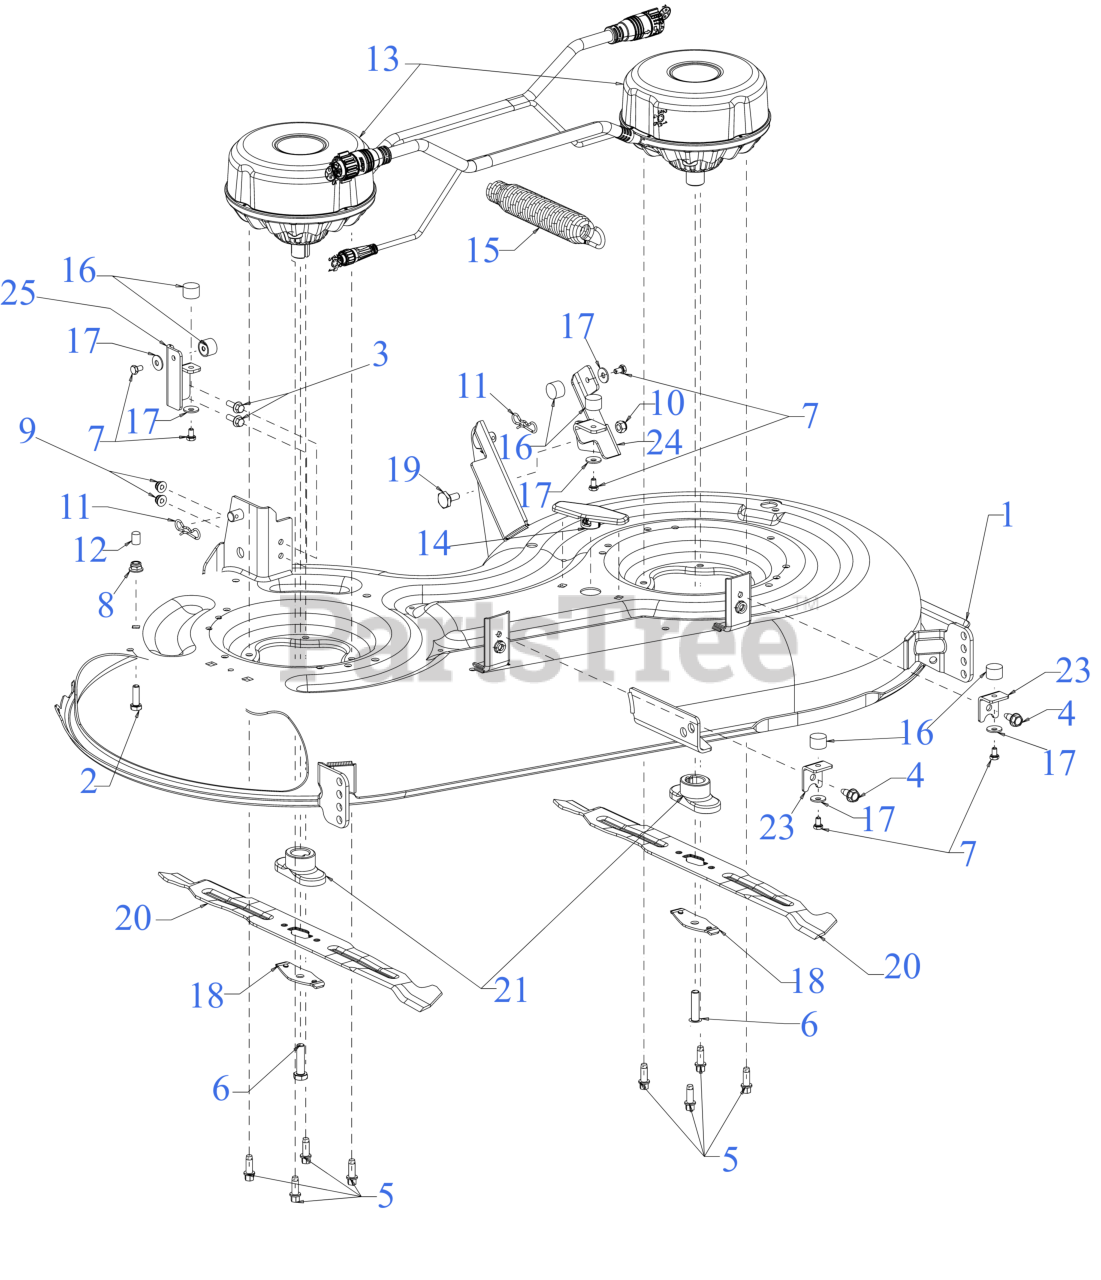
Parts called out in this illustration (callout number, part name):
1	42" DECK
2	SCREW 5/16-18 x 1.0 GR5
3	SCREW 1/4-20 x .75 GR5
4	SCREW M8-1.25 x .750
5	SCREW 5/16-18 x .875
6	SCREW 3/8-24 x 1.50 GR8
7	SCREW M6-1.0X10MM GR8.8
8	FLANGE LOCK NUT 5/16-18
9	FLANGE LOCK NUT
10	HEX NUT
11	BOW TIE COTTER PIN
12	VINYL CAP
13	48V ELECTRIC DECK MOTOR
14	DECK PLUG
15	LIFT ASSIST SPRING (SMALL)
16	BUMPER
17	SPRING WASHER BELL
18	BLADE BELL SUPPORT
19	SHOULDER SCREW
20	21.18" MULCH BLADE (S SHAPE CENTER HOLE)
20	Cub Cadet 42" BLADE SET
21	BLADE ADAPTER (#6 X 1.19 W/S)
23	UPSTOP BRACKET
24	UPSTOP BRACKET (LH)
25	UPSTOP BRACKET (RH)
